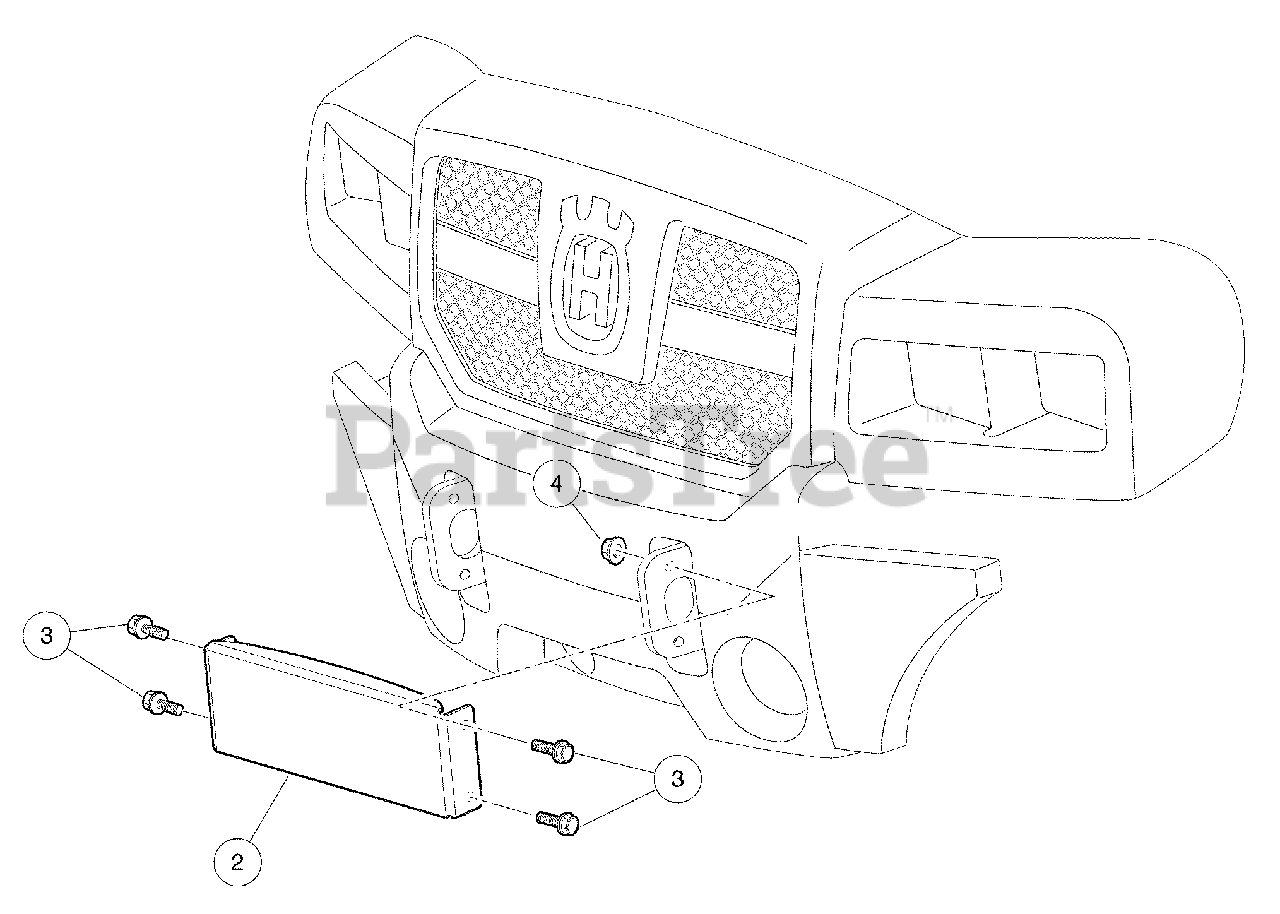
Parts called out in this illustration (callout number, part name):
1	Instl, Bumper Plate, Huv
2	Bumper Plate, Huv
3	Screw, M10 X 1.25 X 30 Hex Blk
4	Nut, Flg, M10 X 1.25 Hex Blk
